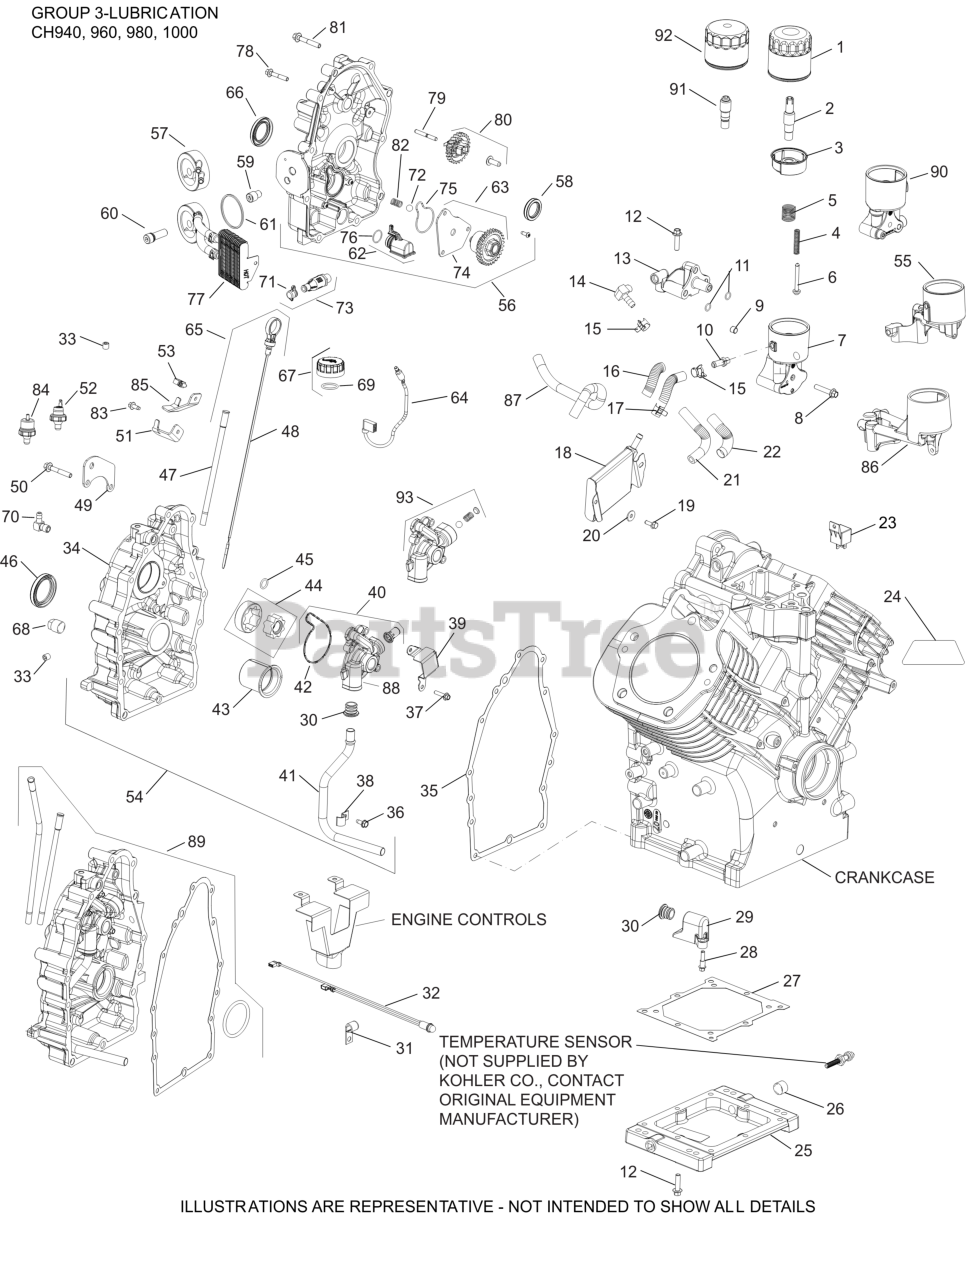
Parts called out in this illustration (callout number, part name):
1	OIL FILTER
3	CUP, OIL FILTER ASSEMBLY
4	SPRING, OIL FILTER VALVE
5	SPRING, OIL FILTER CUP
6	VALVE, OIL FILTER
10	FITTING, BARBED HOSE
11	O-RING, OIL PICK-UP
12	SCREW, FLG M8X1.25X30
15	SPRING CLAMP, HOSE
16	SLEEVE, ANTI ABRASION-USE 25 431 12-S
17	HOSE, OIL RETURN
18	COOLER, OIL ASSEMBLY
20	WASHER, FLAT 1/4"
21	HOSE, OIL SUPPLY
22	SLEEVE, ANTI ABRASION-USE 25 431 12-S
25	OIL RESERVOIR
27	GASKET, OIL RESERVOIR
28	SCREW, SHD THD FRM M6X.0X6.5
29	HOUSING, OIL PICK-UP ASSEMBLY
30	SEAL, PICK-UP TUBE
32	LIGHT, INDICATOR ASSEMBLY
33	PLUG, CTSK PIPE 1/8"
33	PLUG, PIPE 1/2 NPTF SQ CTSK
35	GASKET, OIL PAN
41	TUBE, OIL PICK-UP
42	O-RING, OIL PUMP HOUSING
44	PUMP ASSEMBLY, OIL/GEROTOR
46	SEAL, OIL PTO SIDE, BROWN
47	KIT, DIPSTICK TUBE
51	BRACKET, DIPSTICK TUBE
52	SWITCH, OIL PRESSURE
54	KIT, CLOSURE PLATE
55	KIT, OIL FILTER HOUSING
81	SCREW, HEX FLANGE
83	SCREW, THREAD FORMING
91	NIPPLE, OIL FILTER ASSEMBLY
NI	SCREW, HEX FLANGE M6 X 1
NI	SCREW, HEX HEAD
NI	CLAMP, HOSE OETIKER
NI	HOUSING, OIL PUMP MACH-USE 62 081 38-S
NI	STRAP, LIFTING
